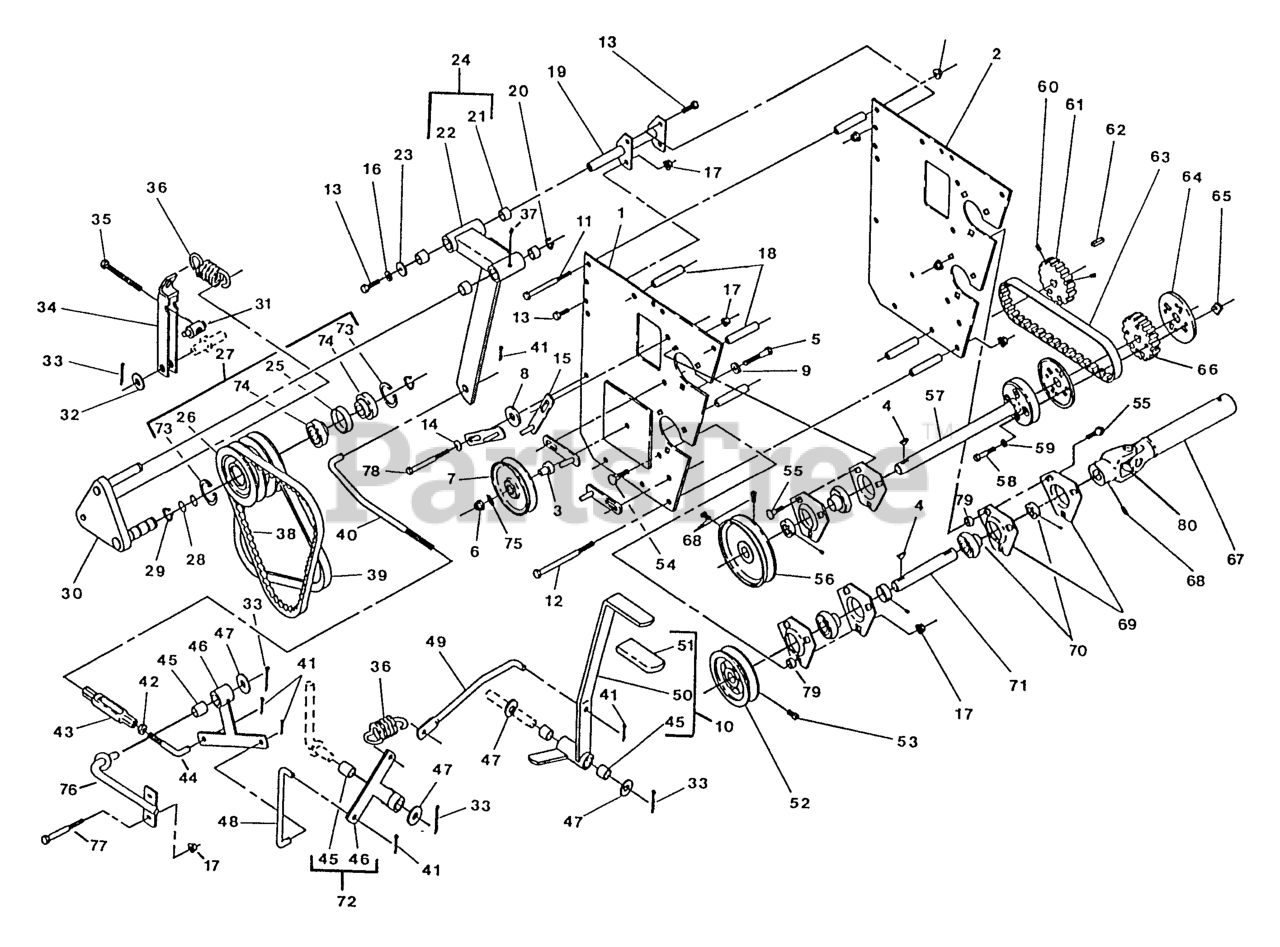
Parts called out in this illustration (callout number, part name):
2	PANEL,POWER TRAIN PNTD
4	KEY-WOODRUFF
12	SCREW-HH
14	WASHER-SPRING
15	GUIDE-BELT
16	WASHER-LOCK
22	Control, Transfer Sheave
24	CNTRL ASSY,TRANS SHV
25	SPACER,TRANSFER BEARING
28	O-RING,
29	RING,RETNG WLDS 5108-100
31	SWIVEL,BELT TENSION
36	SPRING,BELT TENSION
38	BELT,PRIMARY DRIVE
39	BELT,SECONDARY DRIVE
40	ROD,PTO LOW RH THD
44	ROD,PTO RH LOW LH THD
45	SLEEVE-BEARING
49	ROD,PTO UPPER
51	GRIP-LEVER
52	SHEAVE,5.5 B
53	SCREW-SET
59	WASHER-LOCK
63	BELT,DRIVE POSITIVE
69	HOUSING-FLANGE
70	BEARING,W/COLLAR
74	BEARING
76	WLD,BELLCRANK SUPPORT
